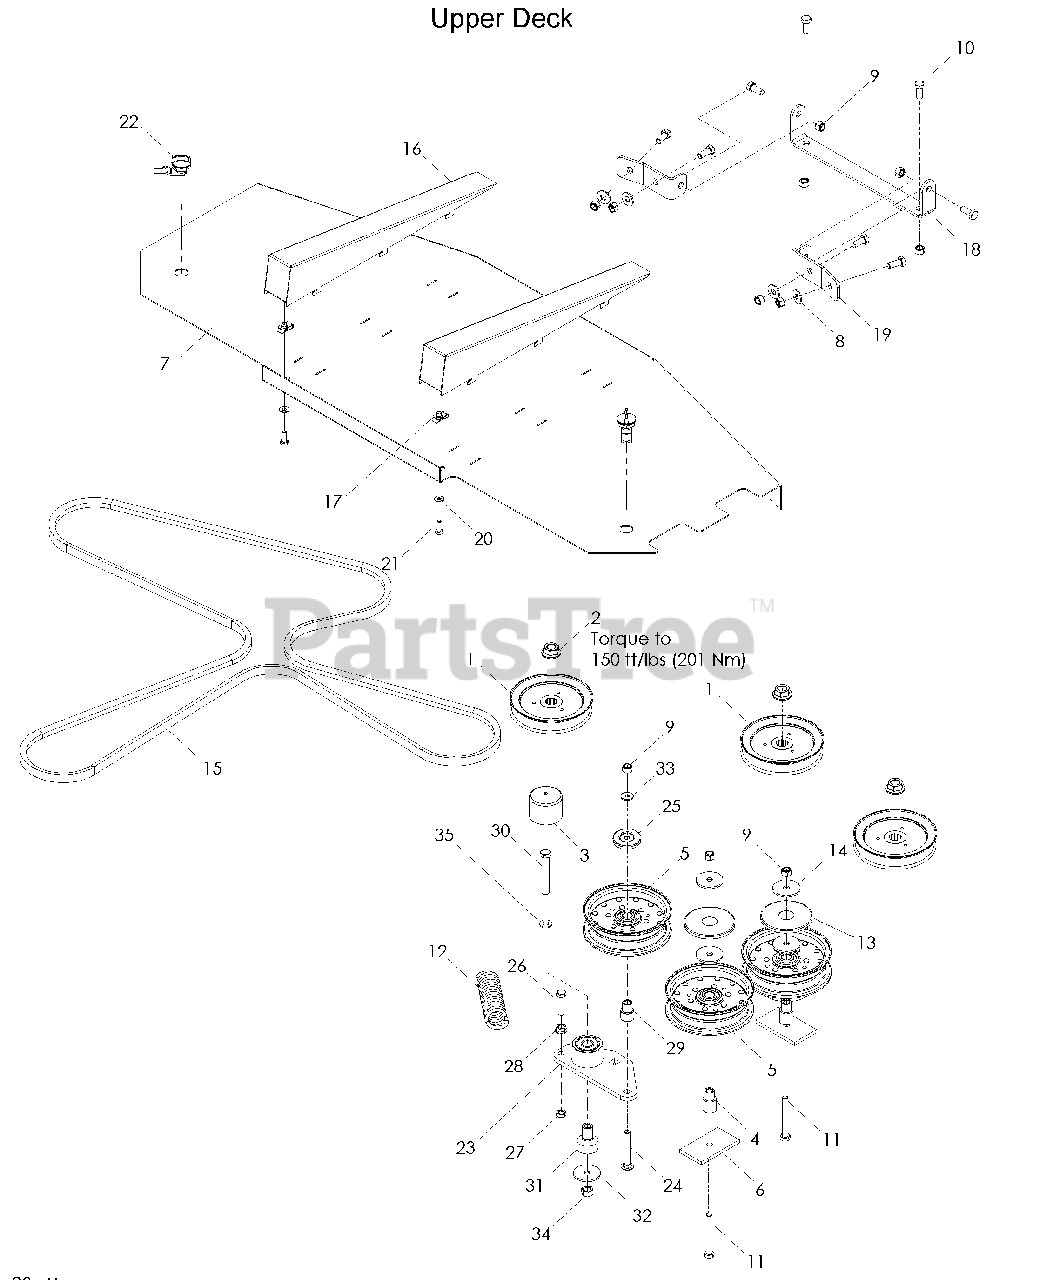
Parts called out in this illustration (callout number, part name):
2	NUT 3/4-16 FLANGE
3	CAP, VINYL
4	BUSHING, IDLER
5	PULLEY, IDLER
6	PAD, PAINTED
7	COVER, BELT, 48
8	WASHER 3/8 FLAT
9	NUT 3/8-16 HEX NYLOC
10	HCS 3/8-16 x 7/8
11	HCS 3/8-16 x 3
13	DUST CAP, TOP
14	WASHER, 3/8 SPECIAL
15	BELT, DECK
17	RETAINER 1/4-20 "U" TYPE
18	HINGE, BIN
19	BASE, HINGE
20	WASHER, 1/4 FLAT SAE
21	HCS 1/4-20 x 3/4
22	LATCH, SHORT WING
23	ARM, IDLER, W/BEARINGS
24	RHSNB 3/8-16 x 2 3/4
25	SHIELD, DUST
26	HCS 3/8-16 x 1 1/2 GR 8
27	NUT 3/8-16 HEX JAM
28	NUT 3/8-16 HEX WHIZLK
29	BUSHING, IDLER
30	HCS 1/2-13 x 3 1/4
31	PIVOT, BEARING
32	WASHER, SUPPORT
33	WASHER, THICK 3/8
34	NUT 1/2 HEX NYLOC
35	WASHER, BELLEVILLE 1/2
